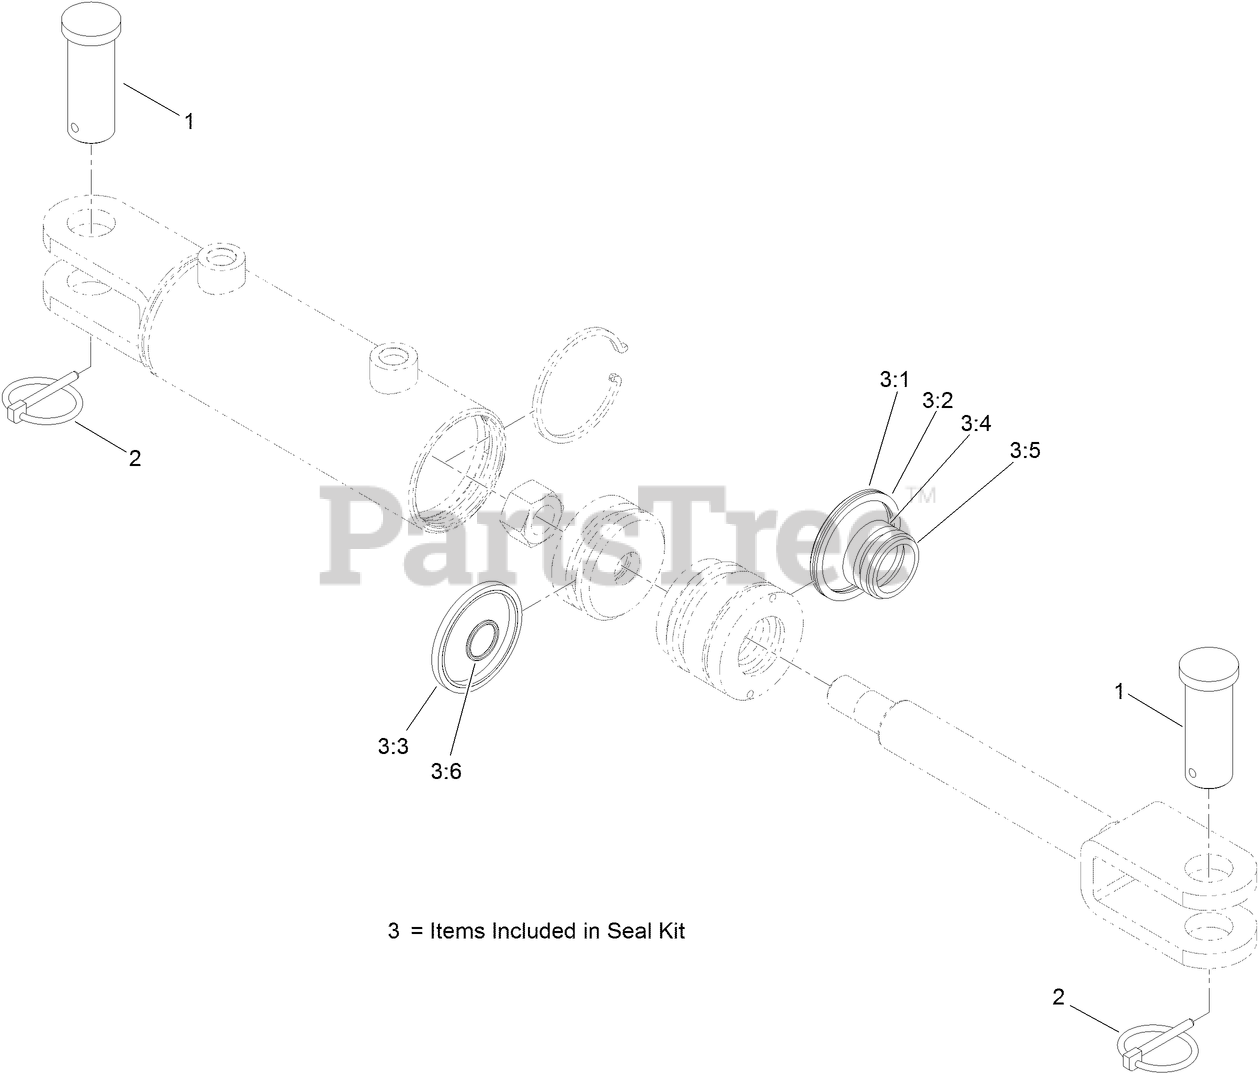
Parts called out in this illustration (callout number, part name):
1	PIN-CLEVIS
2	PIN-LYNCH
3	SEAL KIT
3:1	O-RING
3:2	BACKUP RING
3:3	Psp Seal
3:4	BS SEAL
3:5	Dust Seal
3:6	O-RING
